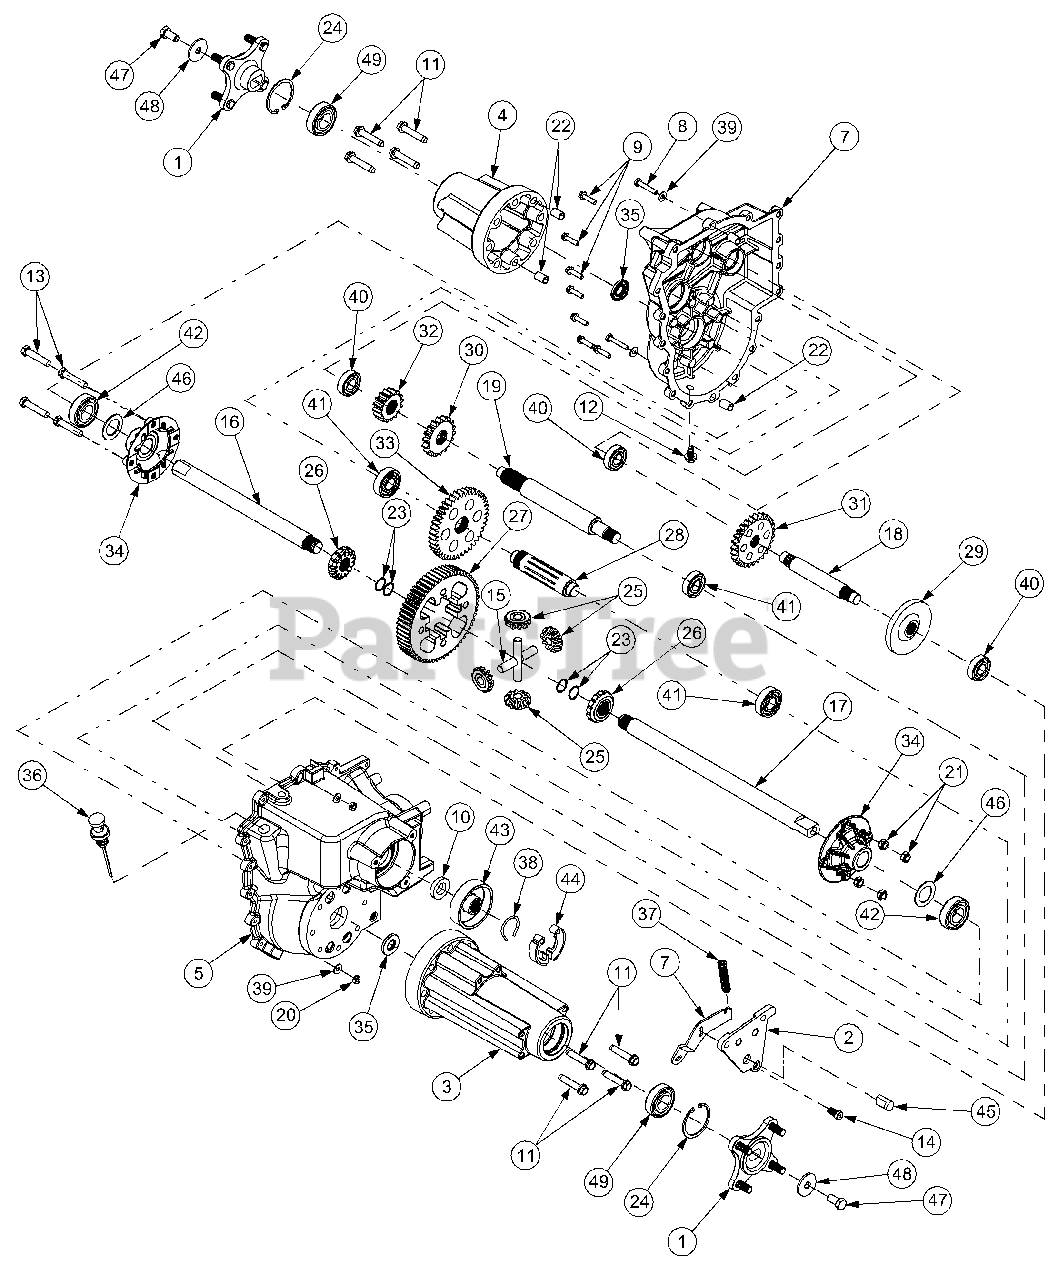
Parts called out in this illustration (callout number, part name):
1	Hub Assembly, Wheel
2	Plate Assembly, Brake
3	Axle Housing, RH
4	Axle Housing, LH
5	Transmission Housing, RH
6	Transmission Housing, LH
7	Brake Arm
8	Screw, Hex Cap, 1/4-20 x 1.5
9	Screw, Hex Wash Hd Tap, 1/4-20 x 1.0
10	Seal, Shift Shaft
11	Screw, TT, 3/8-16 x 1.875
12	Screw, Plug, M14 x 1.5 x .827
13	Screw, Hex Cap, 3/8-16 x 2.0 GR5
14	Screw, Cap, 3/8-16 x .750
15	Shaft, Cross, .500 x 3.005
16	Shaft, Axle, 1.00 x 12.07
17	Shaft, Axle, 1.00 x 15.73
18	Shaft, Drive
19	Shaft, Intermediate
20	Nut, Hex Center Lock, 1/4-20
21	Nut, Hex Insert Lock, 3/8-16 GR5
22	Dowel Bushing
23	Ring, Retaining, .938
24	Ring, Retaining,
25	Gear, Miter, 10T
26	Gear, Miter, 14T
27	Gear, Differential Spur, 60T
28	Shaft, Output, 9T
29	Gear, Bevel, 36T
30	Gear, Spur, 18T
31	Gear, Spur, 27T
32	Gear, Spur, 16T
33	Gear, Spur, 42T
34	Housing, Differential, RH
35	Seal, Oil, 1.0 x 1.499
36	Dipsick, Oil
37	Spring, Compression
38	Spring, Brake Shoe
39	Washer, Flat, .25 x .630 x .0515
40	Bearing, Ball, 17 ID x 40 OD x 12
41	Bearing, Ball, 6204
42	Bearing, Ball, 6205-1
43	Drum, Brake
44	Brake, Shoe
45	Brake, Actuator
46	Washer, Flat, 1.010 x .56 x .060
47	Screw, Hex Lock, 3/8-16 x .75 GR5
48	Washer, Flat, .39 x 1.5 x 1.34
49	Bearing, Ball
